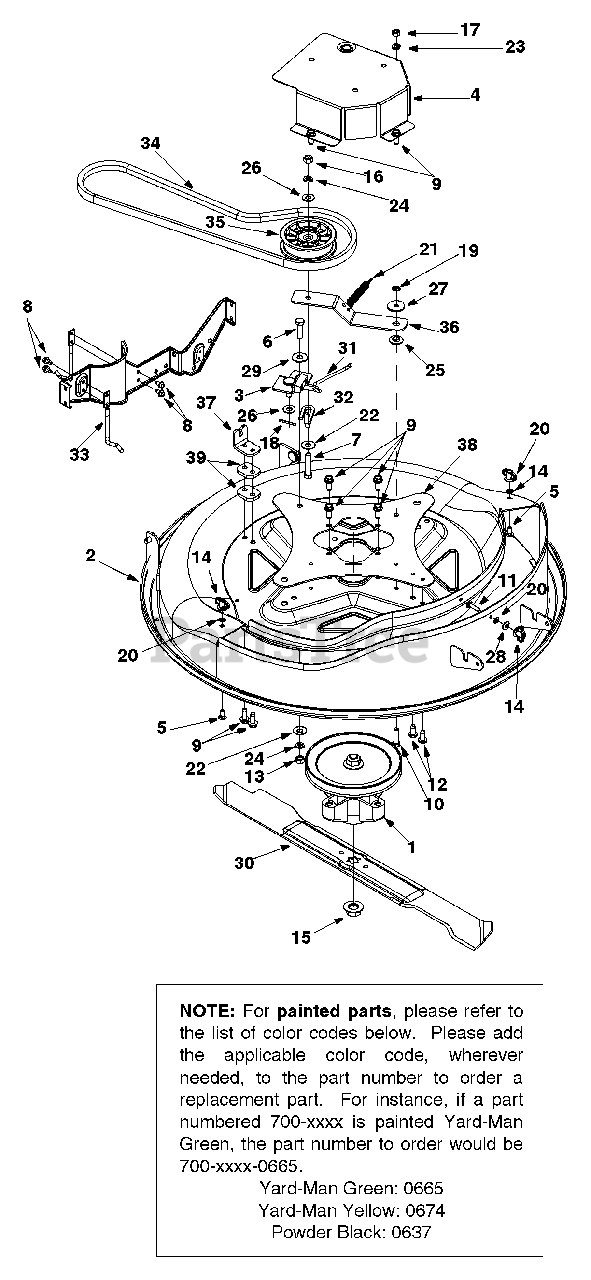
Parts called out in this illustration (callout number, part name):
1	Spindle Assembly
5	Carriage Screw 1/4-20 x .62
6	Hex Bolt 3/8-24 x 1.25 Grade 8
7	Hex Screw 3/8-16 x 1.75 Gr. 5
8	Self-Tapp. Screw 1/4-20 x .5
9	Self-Tapp. Screw 5/16-18 x .75
10	Hex Cap Scr. 5/16-24 x 1.25
11	Carriage Screw
12	Torx Screw 5/16-18 x .75
13	Hex Nut 3/8-24
14	Wing Nut With Bell Washer
15	Flange Nut 5/8-18
16	Hex Nut 3/8-16
17	Hex Nut 5/16-24
18	Cotter Pin
19	Speed Nut
20	Push Nut
21	Extension Spring
22	Flat Washer 3/8 x 1.00 x .030
23	Lock Washer 5/16
24	Lock Washer 3/8
25	Bushing
26	Flat Washer .406 x .875 x .059
27	Flat Washer .330 x 1.25 x .120
28	Flat Washer
29	Spacer
32	Belt Keeper
35	Flat Idler Pulley
